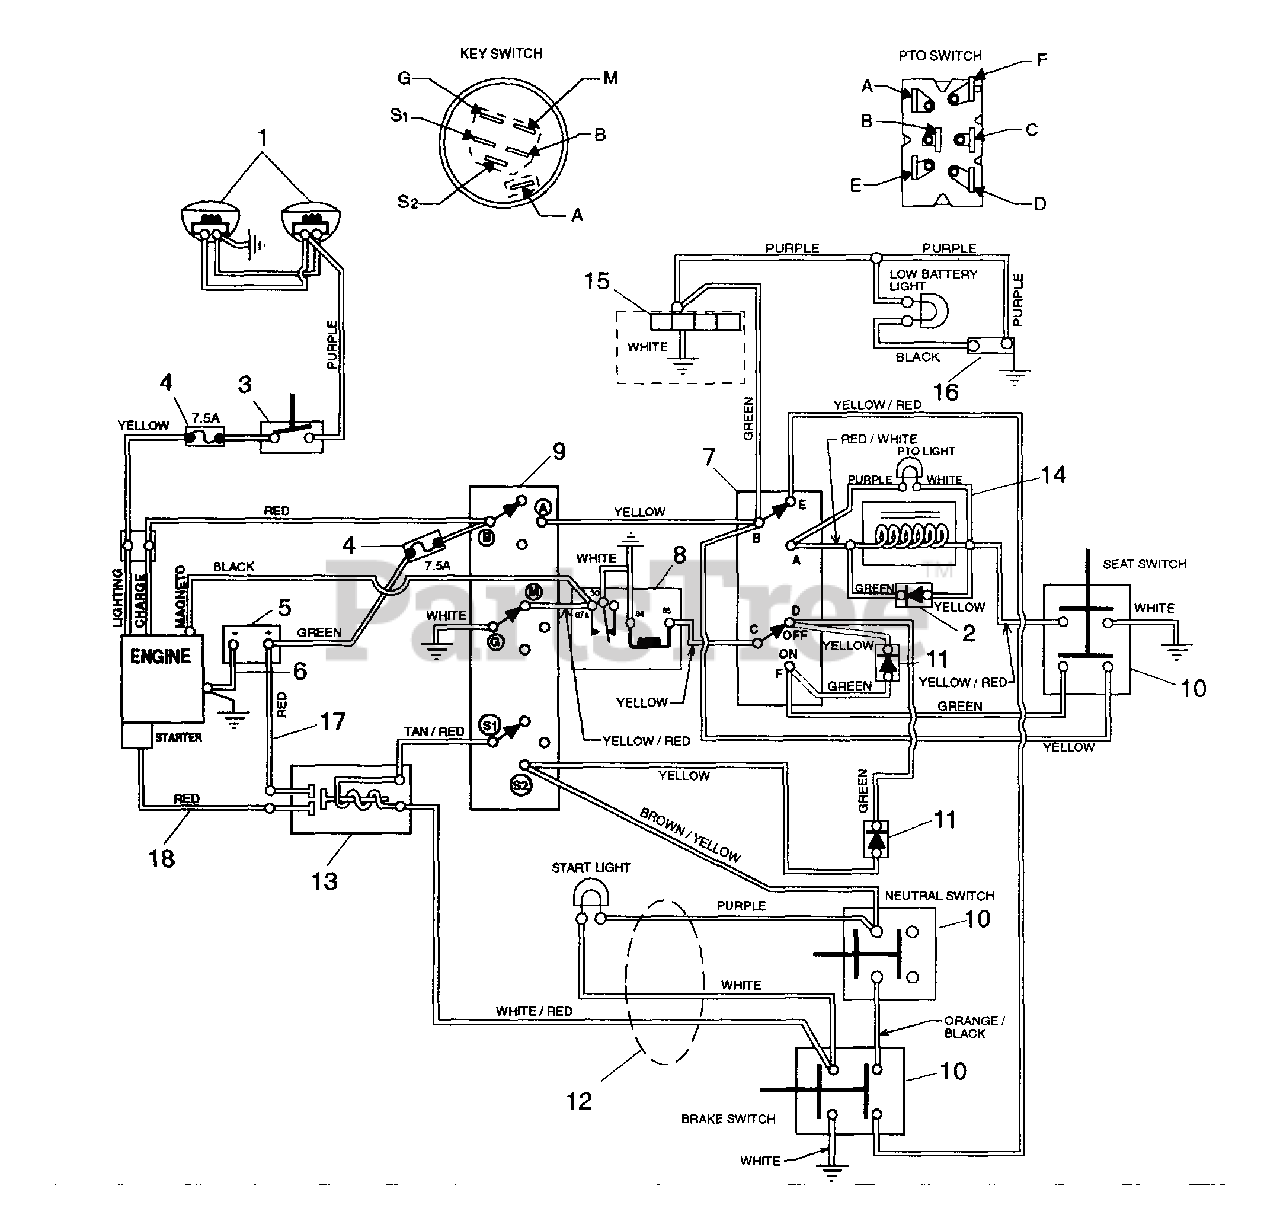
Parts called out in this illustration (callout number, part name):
1	HEADLIGHT- L.H.
1	HEADLIGHT- R.H.
2	DIODE & HOUSING
3	LIGHT SWITCH
4	7.5 Amp Fuse
5	BATTERY W/TUBE
6	GROUND CABLE .31X22.00X.31
7	SWITCH ASSEMBLY- PTO
8	RELAY
9	KEY SWITCH
10	SWITCH- DOUBLE POLE N.O./N.O.
11	MOLDED DIODE PLUG 1 AMP
12	WIRE HARNESS- YT130H
13	SOLENOID
14	ELECTRIC CLUTCH/BRAKE(1.8AMP)
15	HOURMETER
16	VOLTAGE SENSOR
17	START CABLE 22"
18	STARTER CABLE 13"
